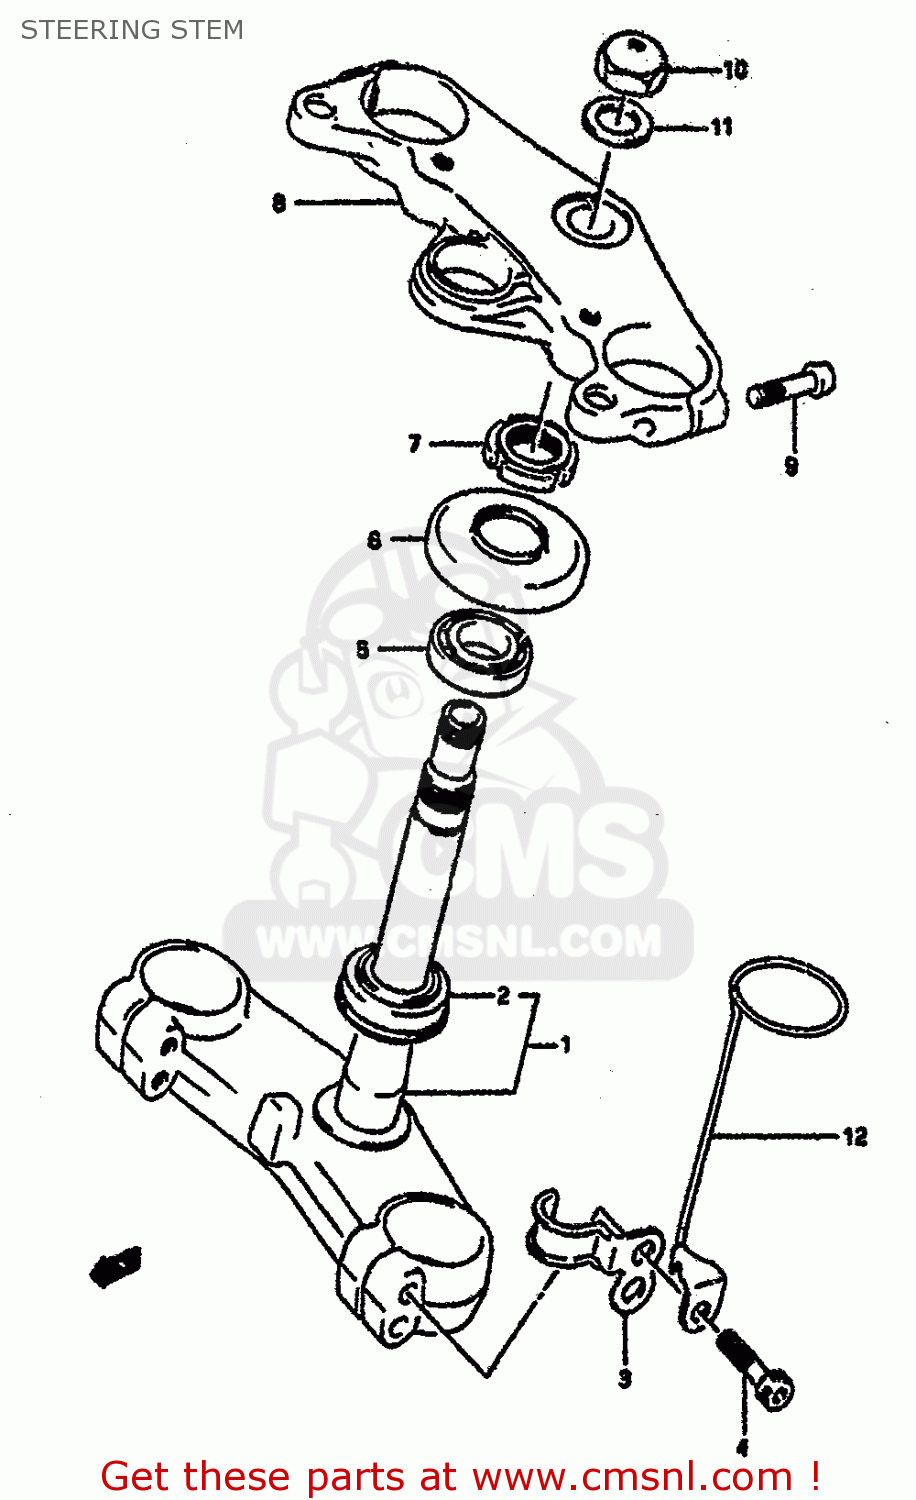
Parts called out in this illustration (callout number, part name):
1	STEM,STEERING
2	BEARING(30X55X17)
3	GUIDE,SPEEDOMETER CABLE
4	BOLT 10X45
5	TAPER,ROLLER BEARING
6	SEAL OIL
7	NUT,STEERING STEM(25X44X10)
8	HEAD,STEERING STEM
9	BOLT,LOWER
10	NUT
11	WASHER(22.5X32X1.6)
12	HOLDER,STEERING DAMPER
